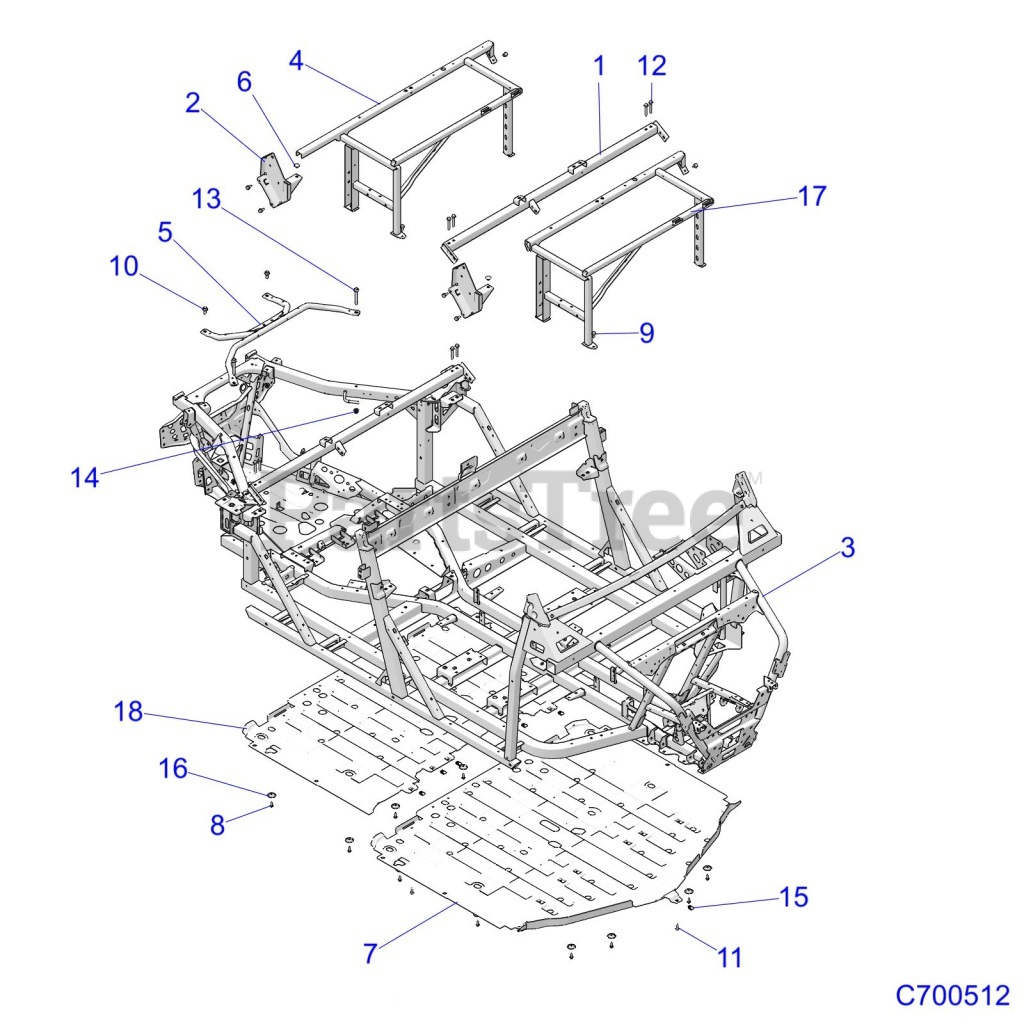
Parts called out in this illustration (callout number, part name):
1	WELD-CROSSBAR,ECOAT
2	WELD-SEAT SPPRT,MNT,PASS,M.BLK
3	WELD-FRAME, MAIN, CREW, M. BLK
4	WELD-SEAT BASE,MAIN,ECOAT
5	WELD-FRAME,BRACE,M.BLK
6	GROMMET-SEAT BASE
7	PLATE-SKID,BLK
8	SCR-M6X1.0X20,HXHD,FLG,TDFM,BL
9	BOLT-M8X1.25X20,HXFLG,TAP/R-OD
10	SCR-M10X1.5X25-8.8 HFS ZOD
11	SCR-TXTH-M6X1.0X25 RIE
12	SCR-HXFL-M8X1.25X55 8.8 ZB
13	SCR-HXFL-M10X1.5X75 8.8 ZY3 NY
14	NUT-M10X1.5 HFN NYLOC ZOD
15	NUT-M6-1.0,U-TYPE (2.5-3.8)
16	WASHER SKID PLATE
17	WELD-SEAT BASE, MAIN, ECOAT
18	PLATE-SKID, REAR, BLK
